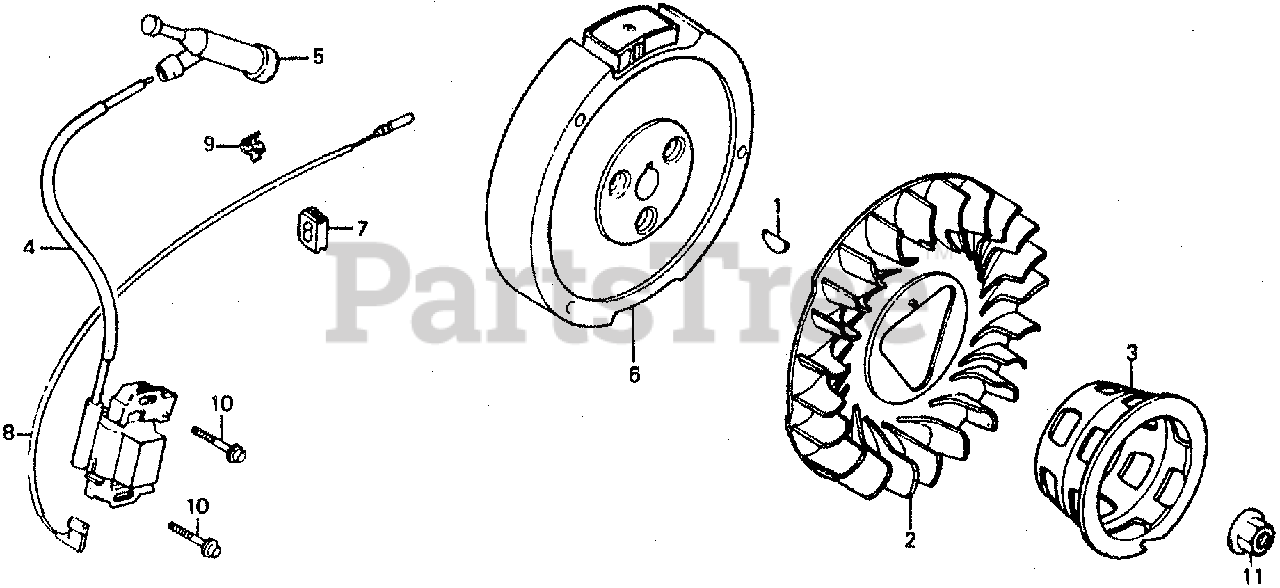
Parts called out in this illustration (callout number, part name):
1	KEY, SPECIAL WOODRUFF (25X18)
2	FAN, COOLING
3	PULLEY, STARTER
4	COIL ASSY., IGNITION
5	CAP ASSY., NOISE SUPPRESSOR (NICHIWA Y-EZ RTFM256)
6	FLYWHEEL
8	WIRE, STOP SWITCH
9	HOLDER, STOP SWITCH WIRE
10	BOLT, FLANGE (6X25)
11	NUT, SPECIAL (14MM)
